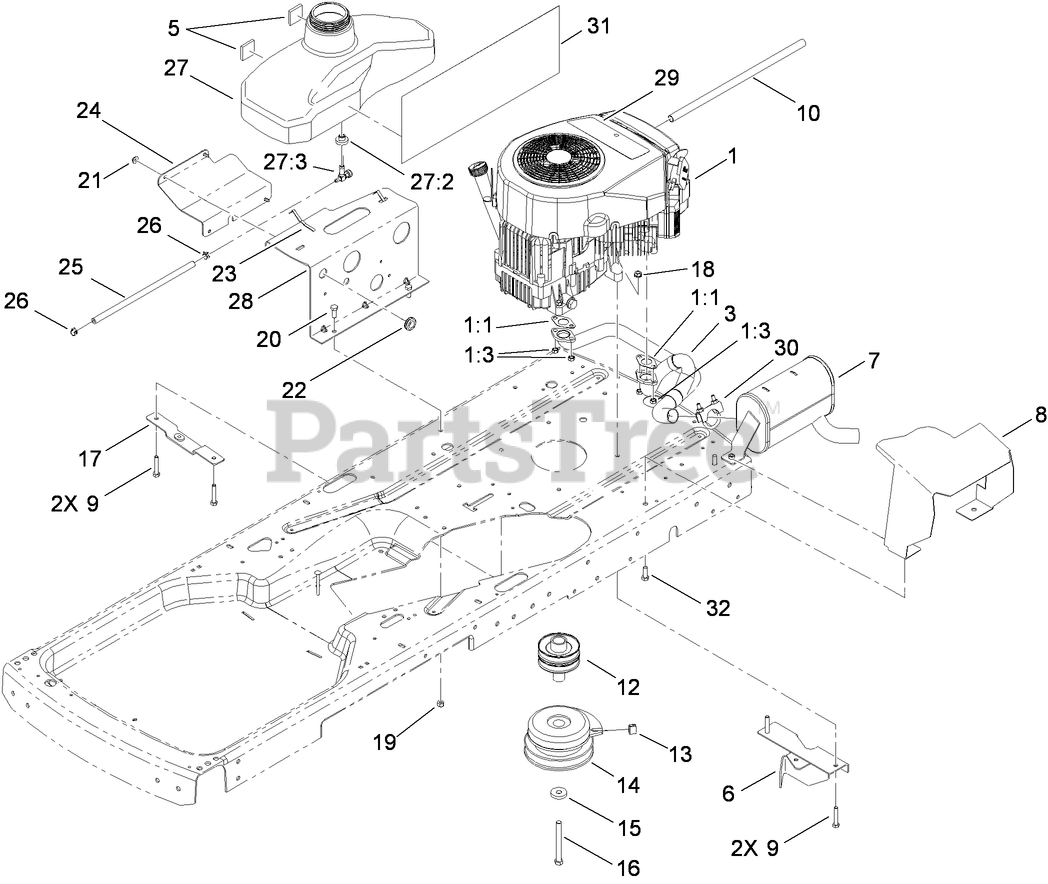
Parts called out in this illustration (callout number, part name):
1	Loose Parts Package
1:1	KAWASAKI#11060-7021
1:3	NUT-M8
3	MANIFOLD
5	FOAM-SWITCH, SEAT
6	BRACKET-PIVOT
7	MUFFLER
8	SHIELD-MUFFLER
9	SCREW-HH
10	TUBE-DRAIN, OIL
12	PULLEY-ENGINE
13	BUMPER
14	CLUTCH-ELECTRIC
15	WASHER
16	SCREW-HH
17	PLATE-MOUNT, IDLER
18	NUT-HF
19	NUT-LOCK, NI
20	SCREW-HH
21	SCREW-HHFTF
22	GROMMET
23	SPRING
24	PLATE-SUPPORT
25	HOSE-FUEL
26	CLAMP-HOSE
27	GAS TANK ASM
27:2	BUSHING
27:3	VALVE-FUEL
28	PLATE-TANK
30	CLAMP-MUFFLER
31	FOIL-SHIELD, HEAT
32	SCREW-HH
